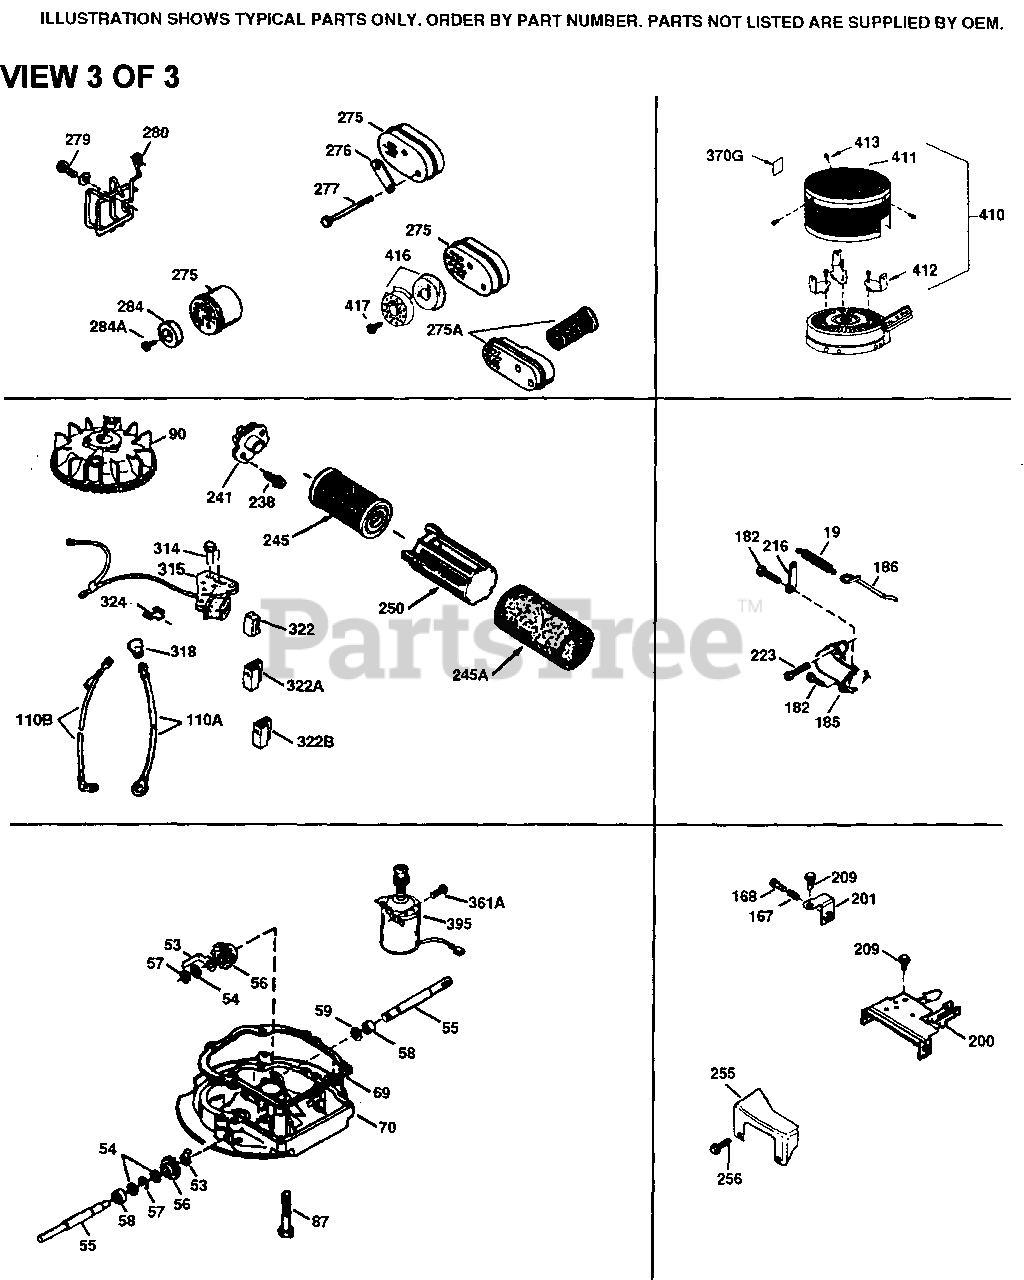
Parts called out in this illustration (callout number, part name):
12A	Breather Cover & Tube (Incl. 12B)
19	Extension Spring
69	* Mounting Flange Gasket
70	Mounting Flange (Incl.72 thru 83)
90	Flywheel
182	Screw, 1/4-28 x 7/8"
185	Intake Pipe
186	Governor Link
216	R.P.M. Adjusting Lever
223	Screw, 1/4-20 x 1"
238	Screw, 10-32 x 49/64"
241	Air Filter Collar
245	Air Filter (Paper) (also available in Packaged Part #740095 (Qty.2))
250	Air Filter Cover (Craftsman)
275	Muffler (Incl. 277)
275A	Spark Arrestor Muffler (Incl. 284,284 A,416,417)(Opti onal)
277	Screw, 1/4-20 x 2-5/16"
284	Muffler Deflector (Incl. 284A) Option al
284A	Screw, 8-32 x 3/8" (Optional)
370K	Starter Decal this)
416	Spark Arrestor Kit (Incl. 417) Option al
417	Screw, 8-32 x 3/8" (Optional)
999	Summer Maintenance Kit (incl. Oil, Sp ark Plug, Air Cleaners (2), & Ultra-F resh)
